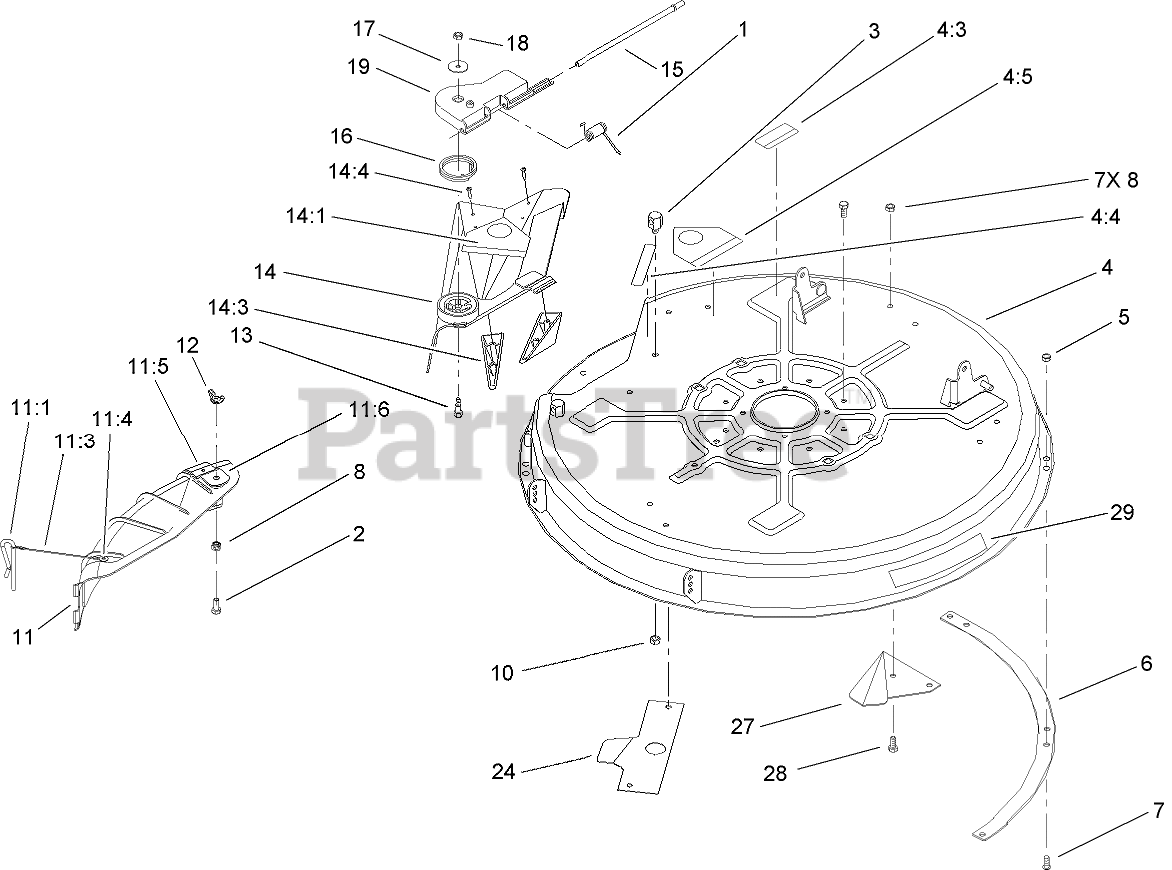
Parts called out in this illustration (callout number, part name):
1	SPRING-TORSION
2	SCREW-HH
3	POST-PIVOT
4	DECK ASM
4:3	DECAL-WARNING
4:4	DECAL-DANGER
4:5	DECAL-DANGER
5	NUT-LOCK, NI
6	RING-DECK
7	SCREW-HH
8	NUT-LOCK, NI
10	NUT-LOCK, NI
11	DISCHARGE COVER ASM
11:1	PIN-LOCKING, CHUTE
11:3	LANYARD
11:4	RIVET-BLIND
11:5	WASHER-PLAIN
12	NUT-WING
13	BOLT-SHOULDER
14	32 INCH DEFLECTOR ASM
14:1	DECAL-DANGER
14:3	KICKER
14:4	SCREW-PPH
15	ROD-HINGE, DEFLECTOR
16	SPRING-TORSION
17	WASHER-FLAT
18	NUT-LOCK, NI
19	PIVOT-HINGE, DEFLECTOR
24	RAMP-DEFLECTOR
28	SCREW-HH
29	DECAL-RECYCLER
